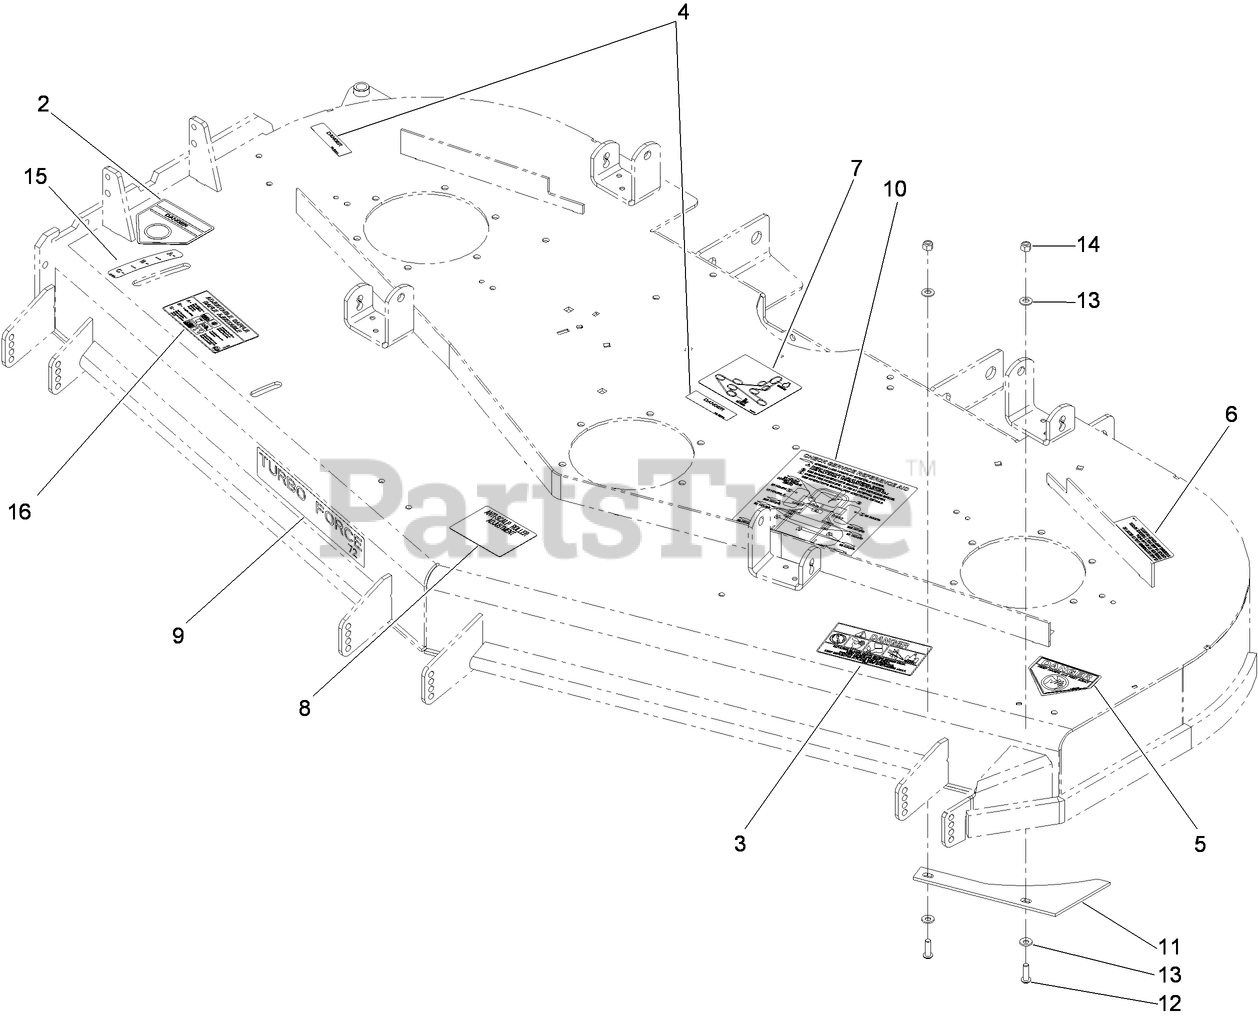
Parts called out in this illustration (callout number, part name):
2	DECAL-DANGER
3	DECAL-DANGER, THROWN OBJECT
4	DECAL-COVER, MISSING
5	DECAL-DANGER
6	DECAL-TORQUE
7	Decal-Routing, Belt
8	DECAL-SCALP, ANTI
10	DECAL-SERVICE, CHECK
11	PLATE-TURBO
12	SCREW-HSBH
13	WASHER-SPRING
14	NUT-LOCK, NI
15	DECAL-SETTING, BAFFLE
16	DECAL-ADJUSTMENT, BAFFLE
